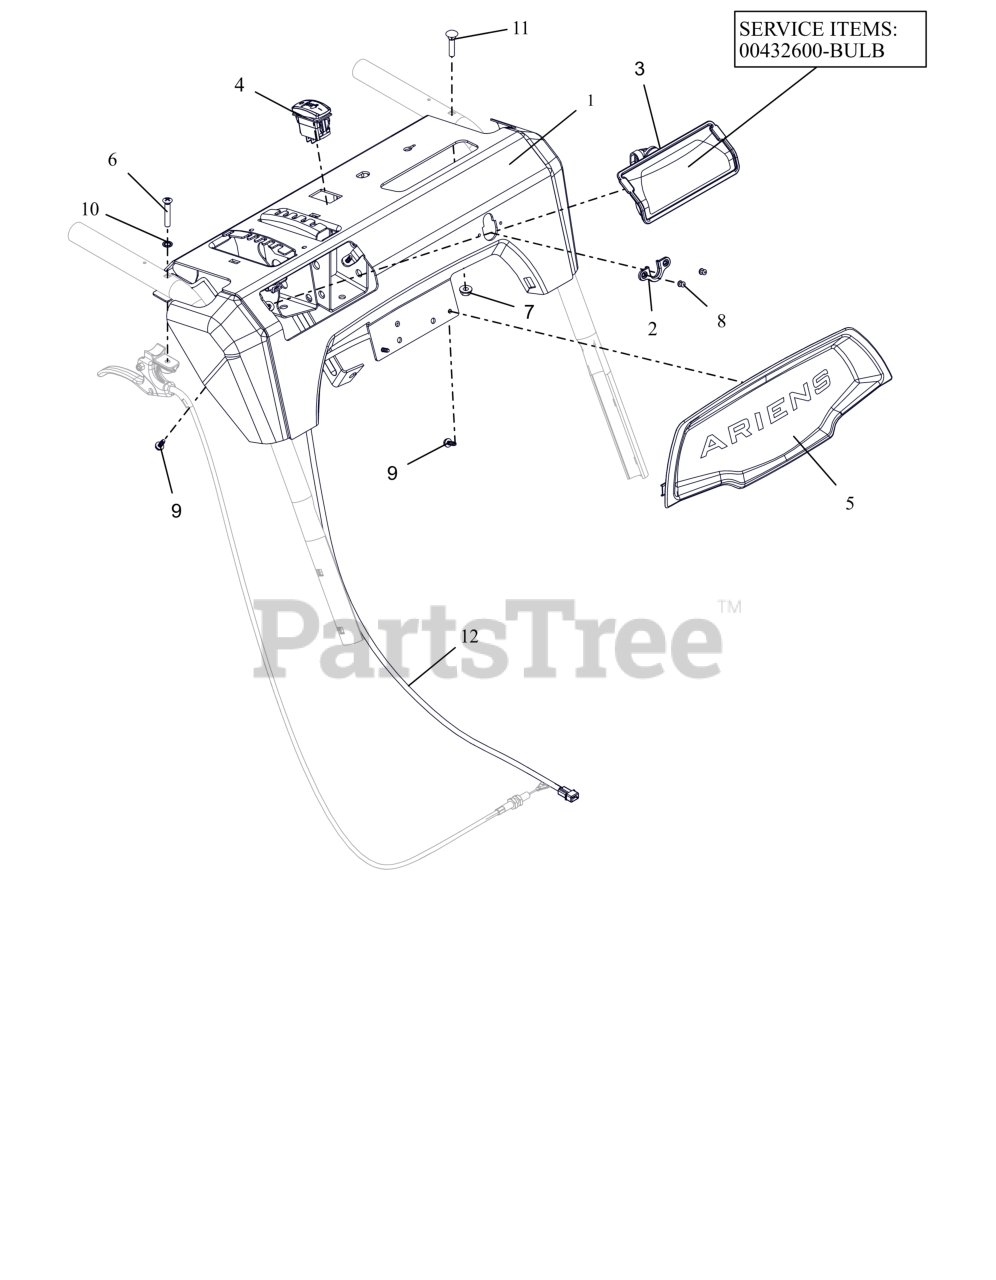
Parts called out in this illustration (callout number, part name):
1	CONTROL PANEL W/DECAL FRIC-TRK
2	GROMMET, CABLE, QUICK TURN 2
3	HEADLIGHT ASY, HALO 20W 2SHOT
3	BULB, LIGHT-HALOGEN 20W
4	SWITCH,ROCKER SPST-ON/OFF
5	BEZEL, DASH - ARIENS LG DASH
6	SCR,OVAL .25-20X1.50 ZCC
7	NUT-LK-CTR-FLG .25-20 ZC120
8	RVT-POP #43 .125X.313 STL ZINC
9	SCR, PLASTIC #10X.50
10	WSHR-LK-INT .250 TH TYA
11	BLT-RDHDXLSQNK.25-20X1.25 G5ZC
12	HARNESS, LIGHT & WARMER
